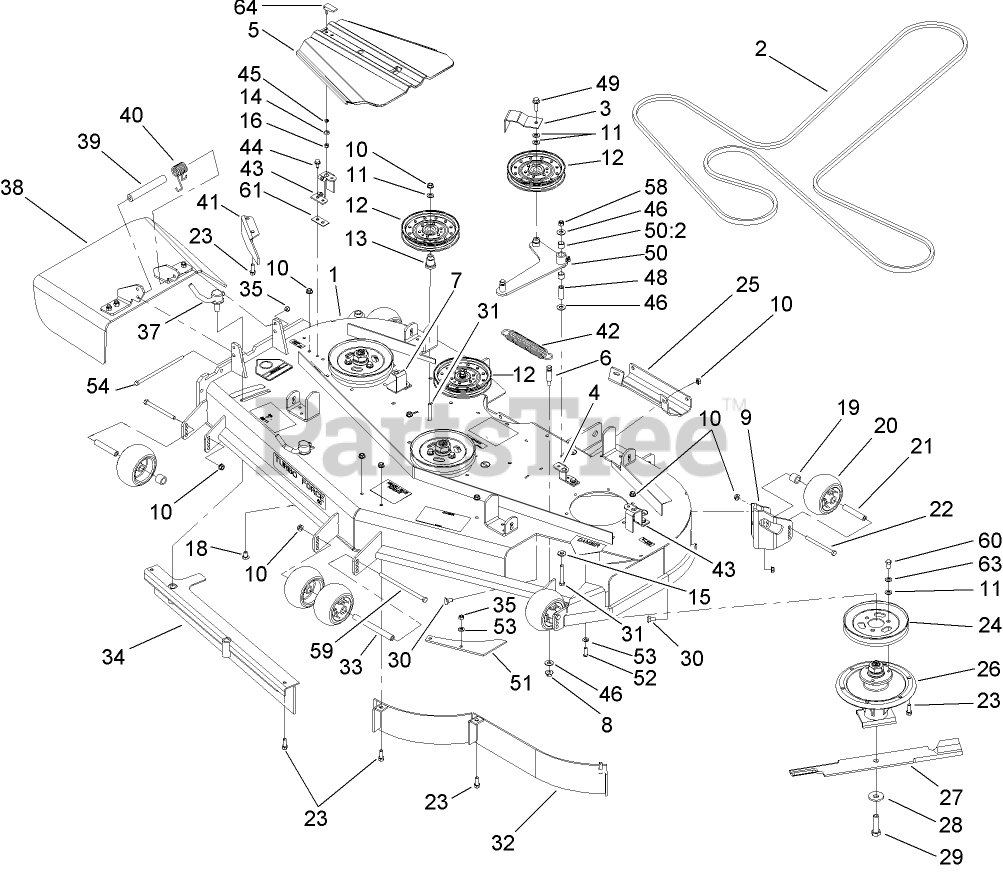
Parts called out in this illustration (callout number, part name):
1	DECK DECAL ASM
2	BELT-V
3	GUIDE-BELT
4	BRACKET-COVER, TALL
5	COVER-BELT
6	PIN-THREADED, SPRING ANCHOR
7	BRACKET-COVER
8	NUT-HF
9	MOUNT-WHEEL, LH
10	NUT-HHF, WHIZ
11	WASHER-FLAT
12	Idler-Flat
13	MOUNT-PULLEY
14	BUSHING-LATCH, SWELL
15	WASHER-BELLEVILLE
16	NUT-LOCK, HH
18	SCREW-CARR
19	TUBE-SPACER
20	ROLLER-SCALP, ANTI
21	TUBE-SPANNER
22	SCREW-HH
23	SCREW-HWH
24	Pulley
25	Plate-Skid
26	SPINDLE ASM
27	BLADE-HI FLOW
28	Washer-Blade Bolt, Heavy
29	SCREW-BLADE
30	SCREW-CARR
31	SCREW-HH
33	SPACER-WHEEL
35	NUT-LOCK, NI
37	LEVER ASM
38	RUBBER DEFLECTOR ASM
39	SPACER
40	SPRING-TORSION
41	BAFFLE-DISCHARGE
42	SPRING-EXTENSION
43	BRACKET-COVER
44	SCREW-HWHTF
45	WASHER
46	WASHER-FLAT
48	BUSHING
49	SCREW-HHF
50	DECK IDLER ARM ASM
50:2	SLEEVE-BEARING
51	PLATE-TURBO
52	SCREW-HSBH
53	WASHER-SPRING
54	SCREW-HH
58	NUT-LOCK, NI
59	SCREW-HH
60	SCREW-HH
61	SPACER-COVER, BELT
63	WASHER-BELLEVILLE
64	HANDLE-LATCH, SWELL
